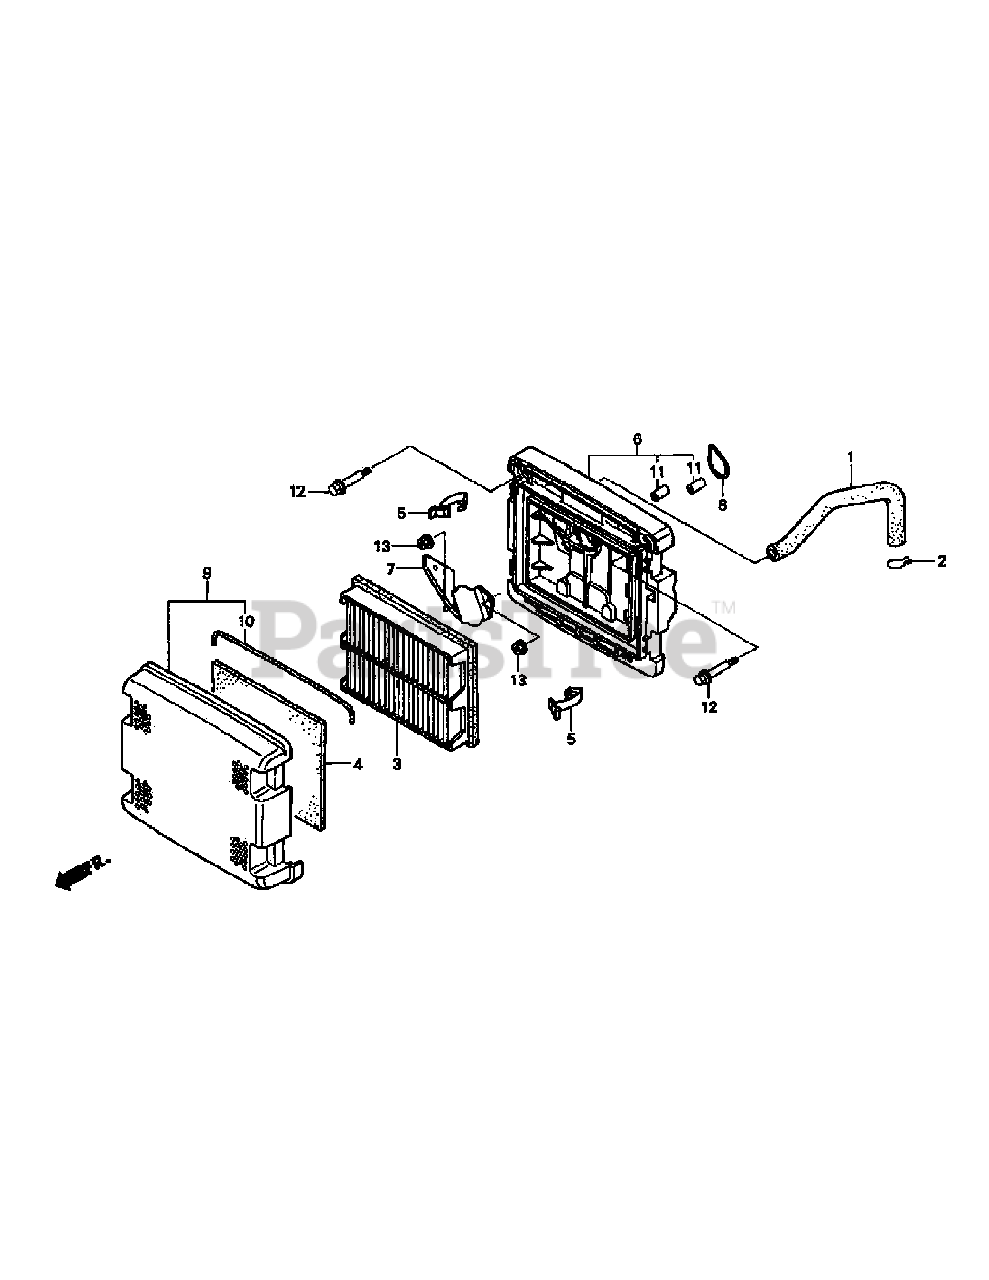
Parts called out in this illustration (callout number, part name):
1	Breather Tube
2	Breather Tube Clip
3	Air Cleaner Element
4	Pre Filter Element
5	Air Cleaner Clip
6	Air Cleaner Housing
7	Air Cleaner Cap
8	Air Cleaner Gasket
9	Air Cleaner Cover Assy.
10	Air Cleaner Cover Seal
11	Air Cleaner Collar
12	Special Bolt (5mm)
13	Flange Nut (6mm)
